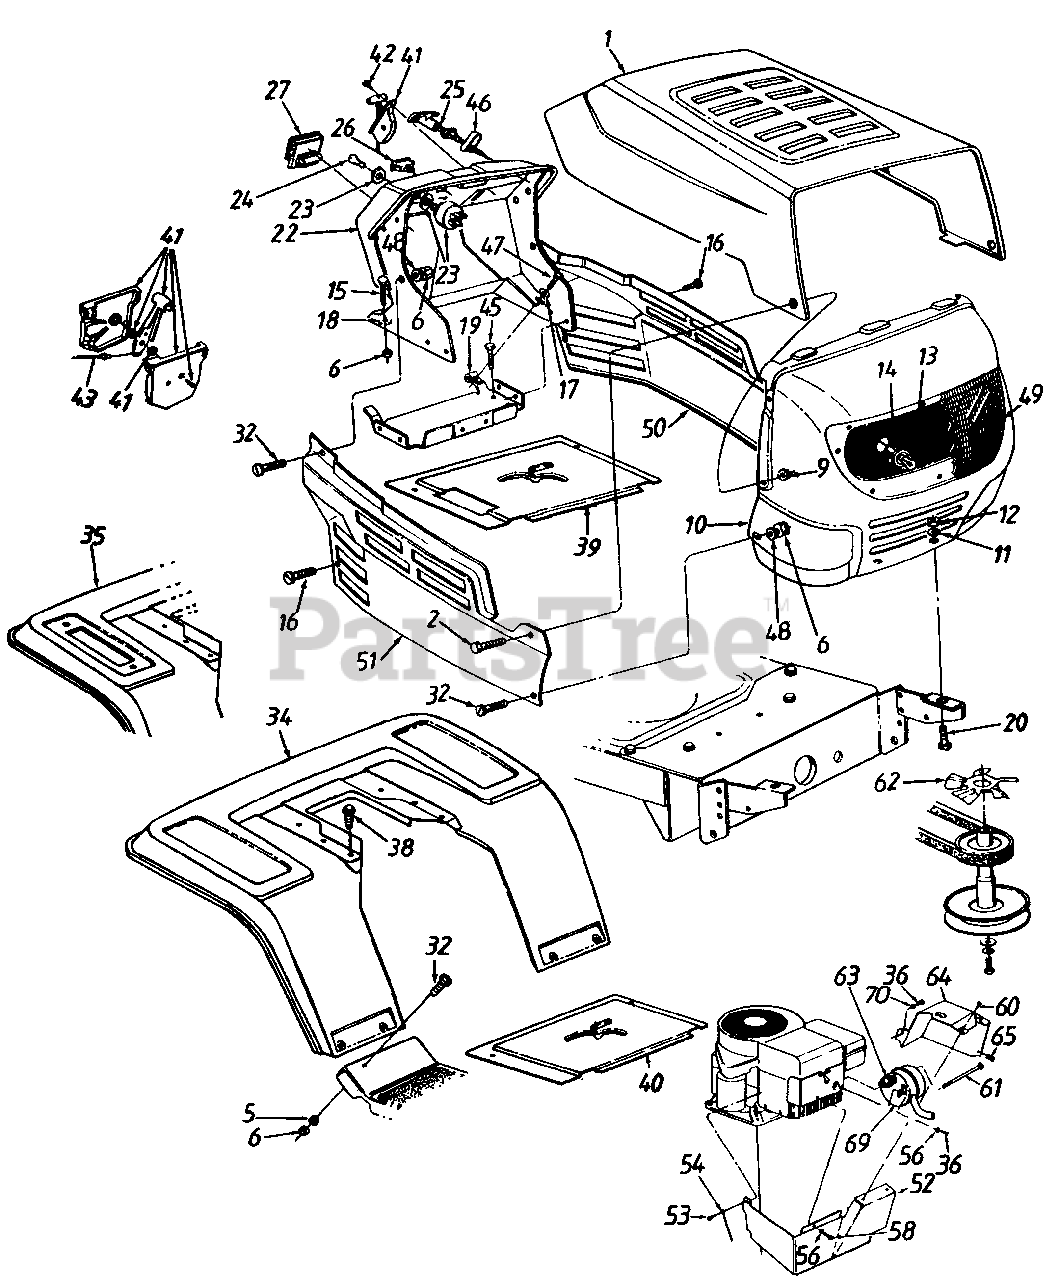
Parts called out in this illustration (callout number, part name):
6	Hex Nut 1/4-20 Thd.
9	Flange L-Nut 1/4-28 Thd.
11	Fl-Wash .344" I.D. x 1" O.D.
12	Hex Nut 5/16-18 Thd.
13	Lamp
14	Socket
15	Carriage Bolt 1/4-20 x .75" Lg.
16	Hex Wash. Hd. TT-Tap Scr. 1/4-20 x .5" Lg.
17	Fl-Wash .281" I.D. x .73" O.D.
18	Bolt Retainer 1/4" I.D.
19	Speed Nut 1/4-20 Thd.
20	Hex Bolt 5/16-18 x .75" Lg.
23	Ignition Switch
24	Ignition Key
25	Choke Control
26	Light Switch
27	Ammeter
32	Truss Mach. Scr. 1/4-20 x .5" Lg.
38	Hex Wash. Hd. AB-Tap Scr. 5/16 x .75" Lg.
41	Throttle Box Ass'y.
42	Truss Mach. AB-Tap Scr. #10 x .5" Lg.
43	Throttle Control Wire
45	Hex Wash. Hd. B-Tap Scr. 5/16-18 x .5" Lg.
46	Choke Retainer
47	Hex TT-Tap Scr. 1/4-20 x .75" Lg.
48	Bell-Wash .265" I.D. x .75"
49	Lens
53	Truss Mach. Scr. 5/16-18 x .75" Lg
54	Ground Wire
56	Spr. Wash. 1/4" I.D.
58	Hex Bolt 1/4-20 x 3/8" Lg.
60	Hex B-Tap Scr. #10 x .38" Lg.
61	Shoulder Bolt
63	Exhaust Gasket
64	Muffler Heat Shield - L.H.
65	Speed Nut #10-24 Thd.
69	Muffler
70	L-Wash. 1/4" I.D.
